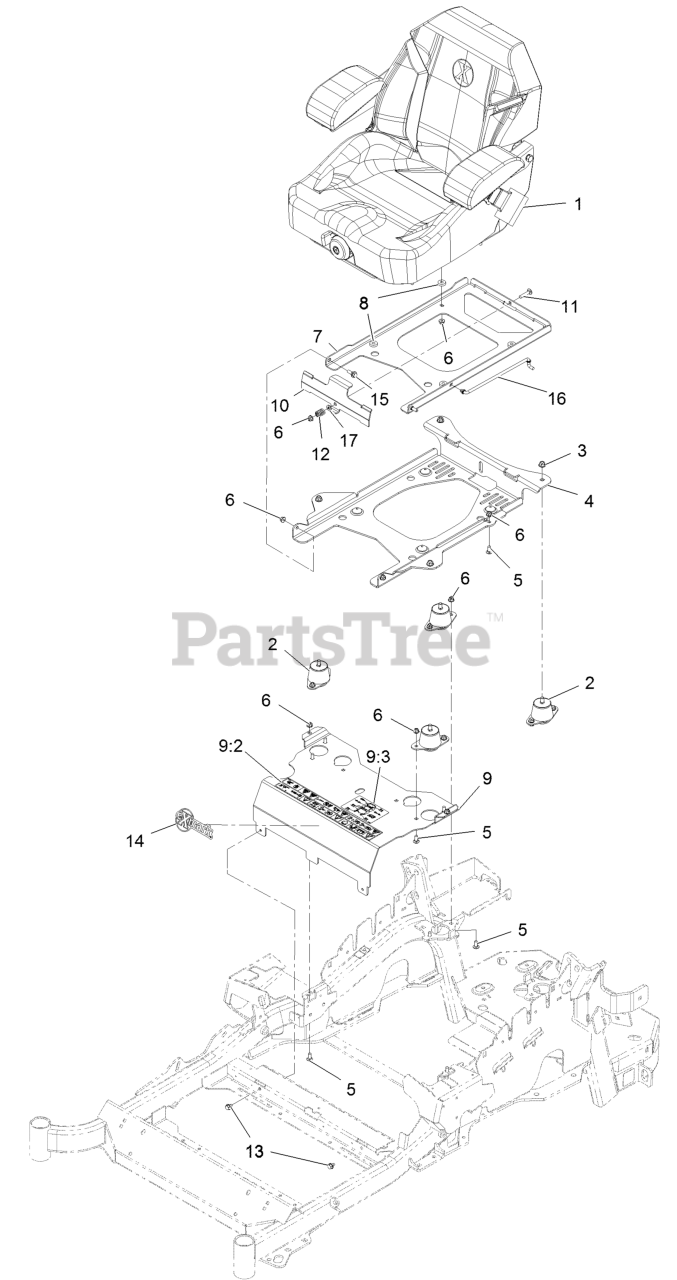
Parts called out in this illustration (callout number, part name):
1	KIT-SUSPENSION SEAT
2	ISOLATOR-SEAT
3	NUT-HF, NI
4	PLATE-TILT, SEAT SUPPORT
5	SCREW-CARR
6	NUT-HF, NI
7	PLATE-FRAME, SEAT
9	MOUNT-SEAT
9:2	DECAL-CONSOLE
9:3	DECAL-SERVICE AID
10	PLATE-LATCH, SEAT
11	BOLT-CARR
12	SPRING-COMPRESSION
15	SCREW-SHOULDER
16	ROD-PROP
17	WASHER-PLAIN
